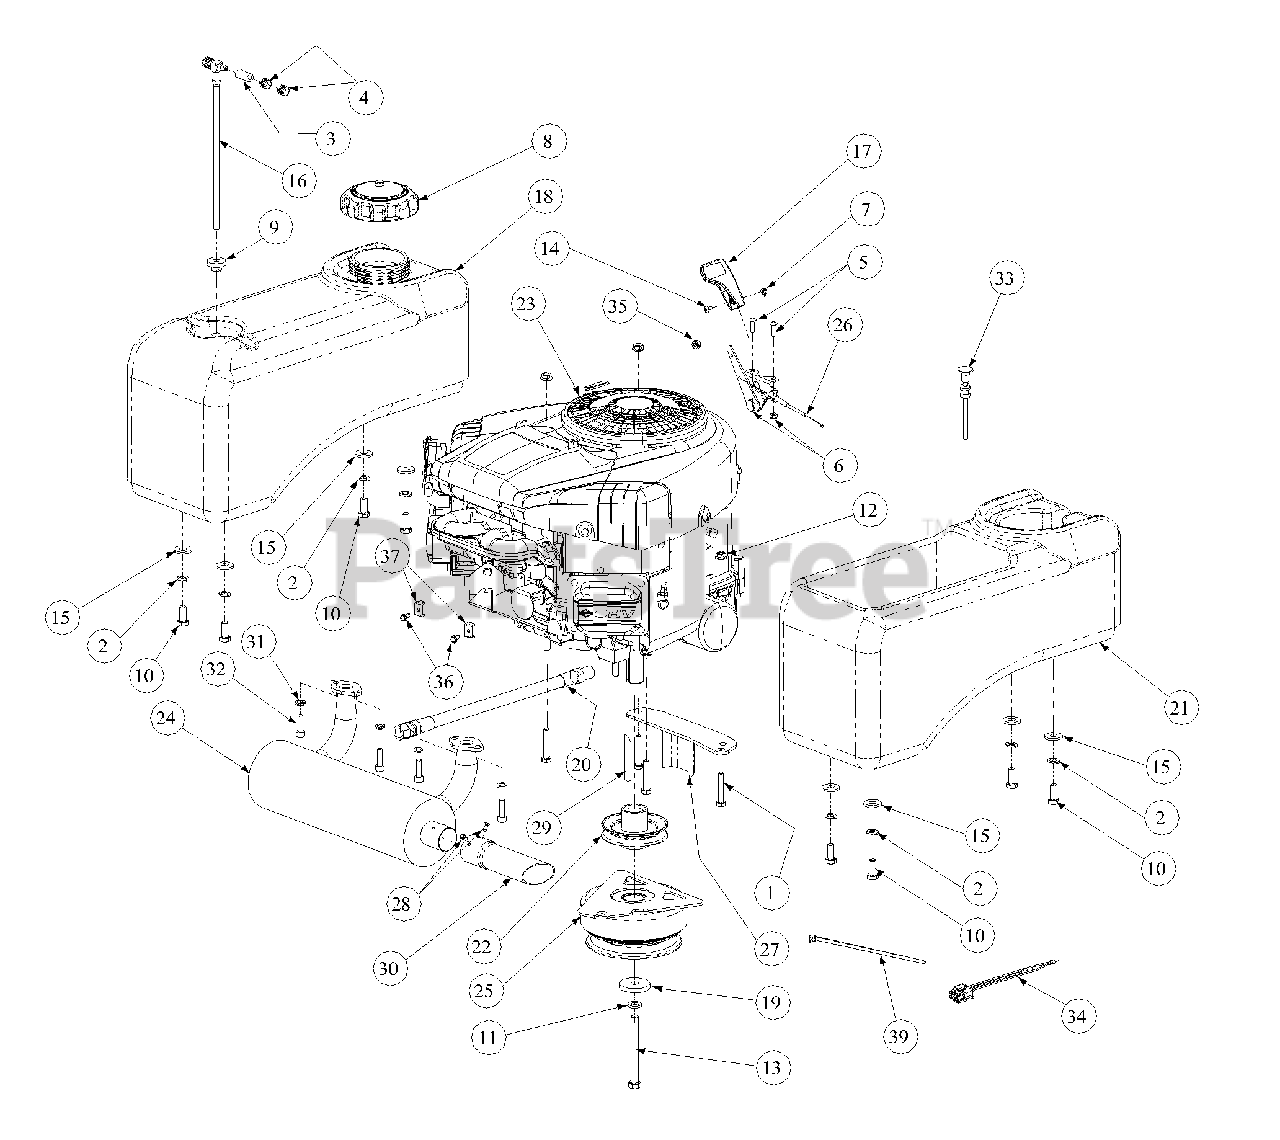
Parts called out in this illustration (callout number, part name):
1	Hex Head Cap Screw, 5/16-18 x 1-3/4
2	Lock Washer, 3/8 Zinc
3	Hose, 1/4" Fuel Line
4	Clamp, Union
5	Self Tapping Screw, 10-32 x 1/2
6	Lock Nut, Nylon Insert, 10-32
7	Nut, w/ Star Washer
8	Fuel Cap
9	Fuel Tank Groment
10	Hex Cap Screw, 3/8-16 x .88
11	Lock Washer, 7/16
12	Lock Nut, Hex Flange, 5/16-18
13	Hex Cap Screw, 7/16-20 x 3.0
14	Machine Screw, 8-32 x .375
15	Flat Washer, .406 ID x 1.0 OD x .105
16	Fuel Pickup Fitting
17	Throttle Control Knob
18	Fuel Tank
19	Flat Washer, 7/16 ID x 1.75 OD x .250
20	Oil Drain Extension Hose
21	Utility Bin
22	Electric PTO Engine Pulley
23	22HP Briggs Engine
24	Briggs Muffler
25	Ogura DX11 Electric Clutch
26	Throttle Control Cable
27	Clutch Retainer Assembly
28	Screw, 8-32 x .375, Hex Washer
29	Key, 1/4 x 1/4 x 2.75
30	Exhaust Pipe
31	Lock Washer, 5/16
32	Socket Head Cap Screw, 5/16-18 x 1.00
33	Choke Cable
34	Harness Adaptor
35	Starter Side Lock Nut 1/4-20
36	Screw, #10-32 x 0.500
37	Throttle Cable Clamp
38	Hour Meter Harness
39	Cable Tie, 3/16 x .05 x 7.4
